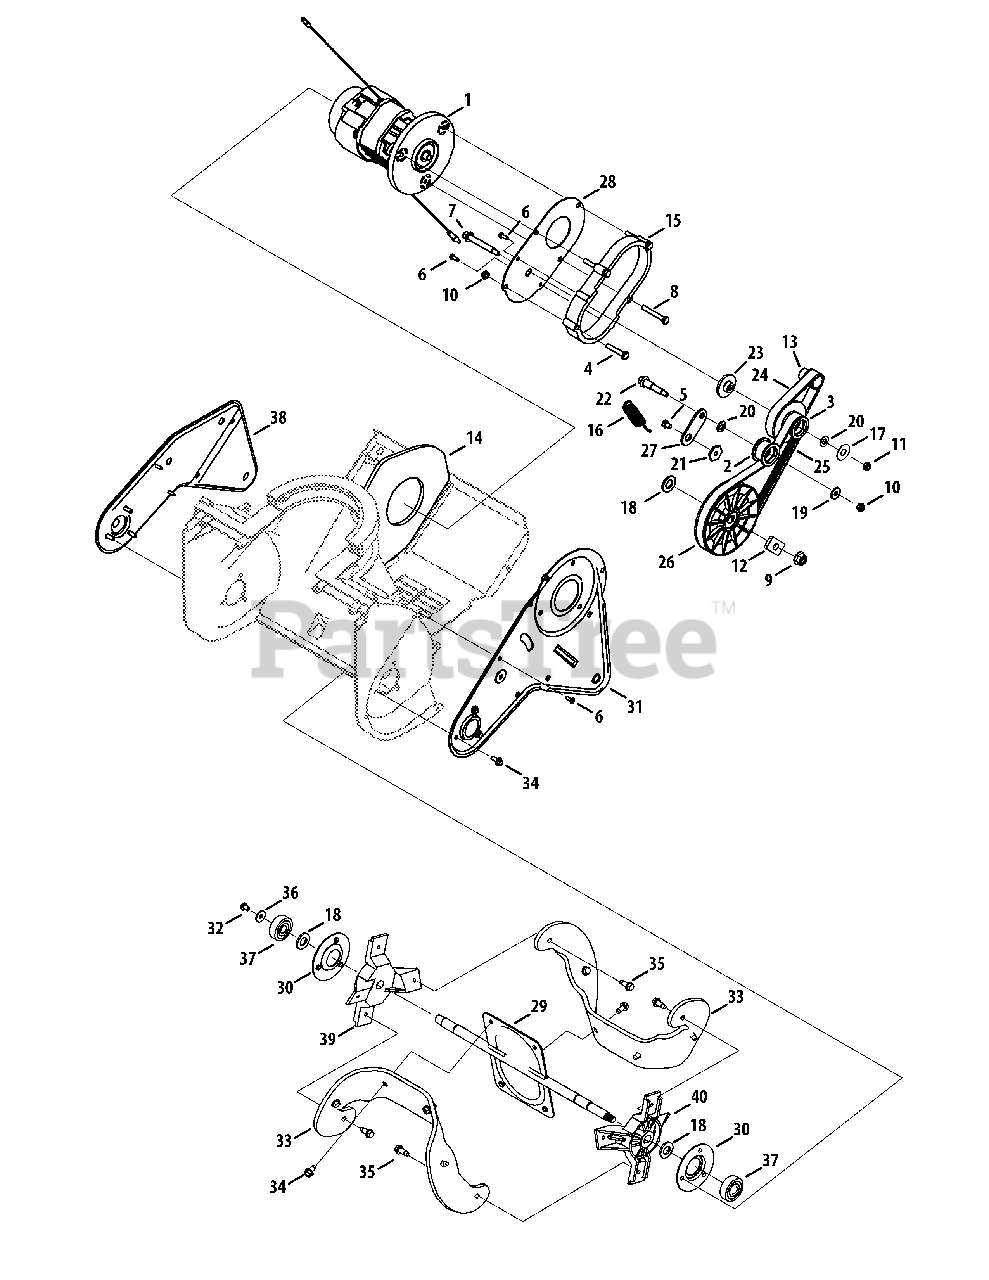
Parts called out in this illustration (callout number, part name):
1	Motor Assembly (Incl. Ref 13)
2	Pulley Assembly, Idler
3	Pulley Assembly
4	Screw, M6-1, 35.00
5	Screw, Hex Screw, M6 x 8mm
6	Screw, Tap, M4.2 x 1.4 x 13
7	Screw, Hex Flange, M8-1.25, 60mm
8	Screw, M6-1, 45.00
9	Nut, Flange Lock, 3/8-16, Nylon
10	Nut, Hex Lock, M6-1
11	Nut, Hex Lock, M8-1.25, Nylon
12	Plate, Drive Pulley
13	Pulley, 5mm, 15 Tooth
14	Gasket, Foam
15	Spacer, Motor Mount
16	Extension Spring, Idler
17	Washer, Flat, .406 x 1.0 x .030
18	Washer, Flat, M12
19	Washer, Flat, 6.4 Id x 18 OD
20	Washer, Flat, 8.4 x 16 x 1.60
21	Spacer, Shoulder, Hex, M6
22	Screw, Shoulder
23	Spacer, 8.35 x 16 x 11.65
24	Belt, Sync
25	Belt, Poly, 6 Rib
26	Pulley, Auger, 6 Rib
27	Bracket, Idler
28	Plate, Motor Mount
29	Auger Weldment
32	Screw, Hex Screw, M6 x 8mm
33	Paddle Auger, Rubber
34	Screw, Self-tapping, 1/4-20, 0.500
35	Screw, 1/4-10 x .625
36	Washer, Flat, 6.4 Idx18 OD
37	Bearing, Ball, 12 x 37 x 12
39	Bracket, Paddle, Mount, LH
40	Bracket, Paddle, Mount, RH
